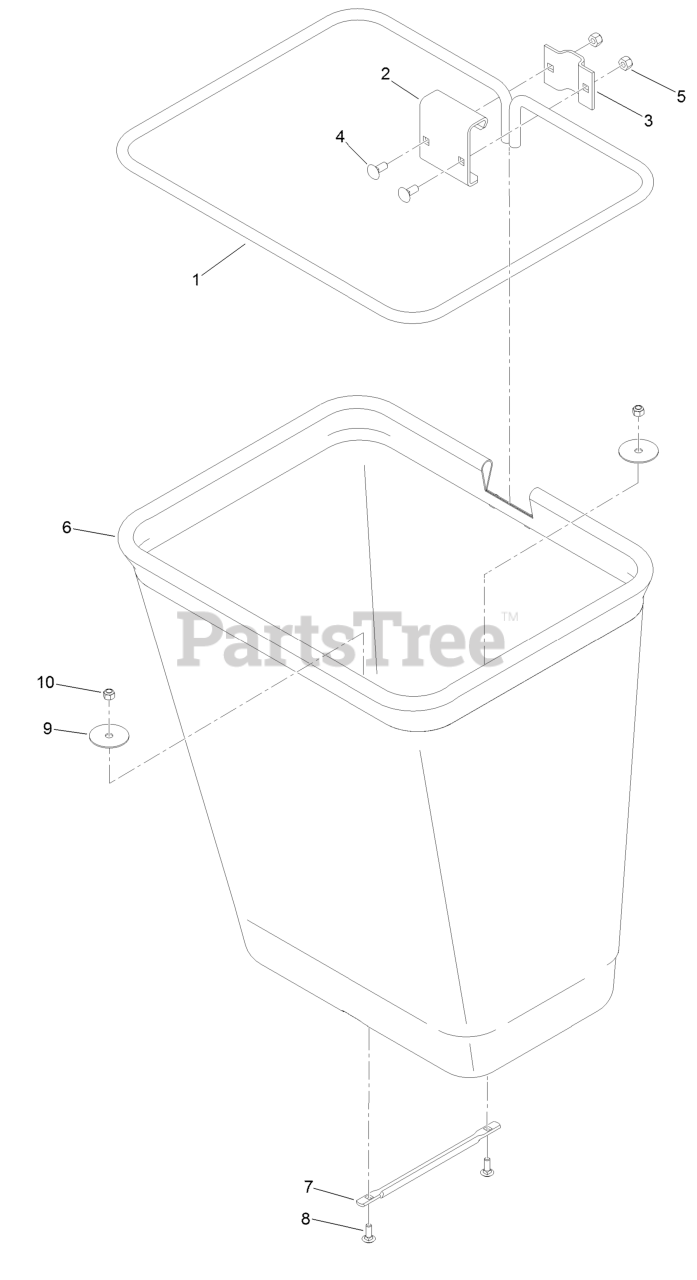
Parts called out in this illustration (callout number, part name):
1	Frame-Bag
2	Hanger-Bag
4	Bolt-CARR
5	Nut-Lock, NI
6	Bag ASM
7	Handle-Bag
8	Bolt-CARR
10	Nut-Lock, NI
